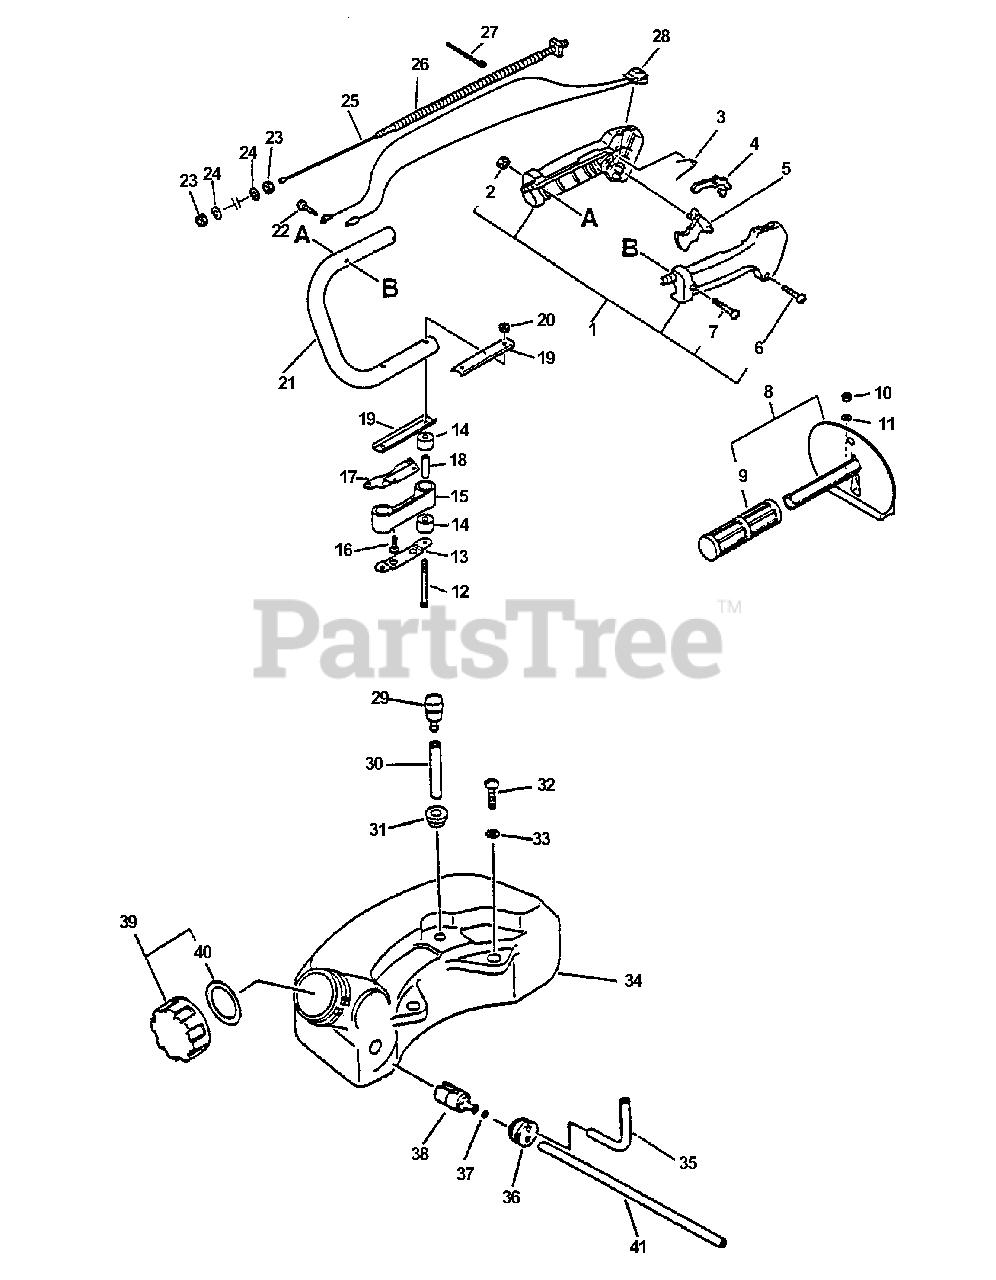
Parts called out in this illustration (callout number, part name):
1	THROTTLE CONTROL ASSY
3	SPRING, LOCKOUT LEVER
4	LOCKOUT, THROTTLE
5	TRIGGER, THROTTLE
6	SCREW - 3X25
7	SCREW - 5X30
8	HANDLE ASSY - FRONT
9	GRIP, HANDLE
11	WASHER - 6
12	SCREW - 5X60
13	PLATE, CUSHION
15	BRACKET, HANDLE
16	SCREW - 5X16
18	SPACER
19	BRACKET, HANDLE - LOWER
20	LOCKNUT - 5
21	HANDLE - REAR
22	SCREW - 5X10
24	WASHER - 6
25	CABLE, THROTTLE
27	TIE, CABLE
28	IGNITION SWITCH ASSY
29	VENT, FUEL TANK
30	PIPE - 3X6X35 -- BLACK
31	GROMMET
32	SCREW - 5X16
33	WASHER - 5
34	TANK, FUEL
35	PIPE - 3X5X180 -- BLACK
36	GROMMET
37	CLIP - 6
38	FILTER, FUEL
39	CAP ASSY
40	GASKET, CAP
41	PIPE - 3X6X110 -- CLEAR
